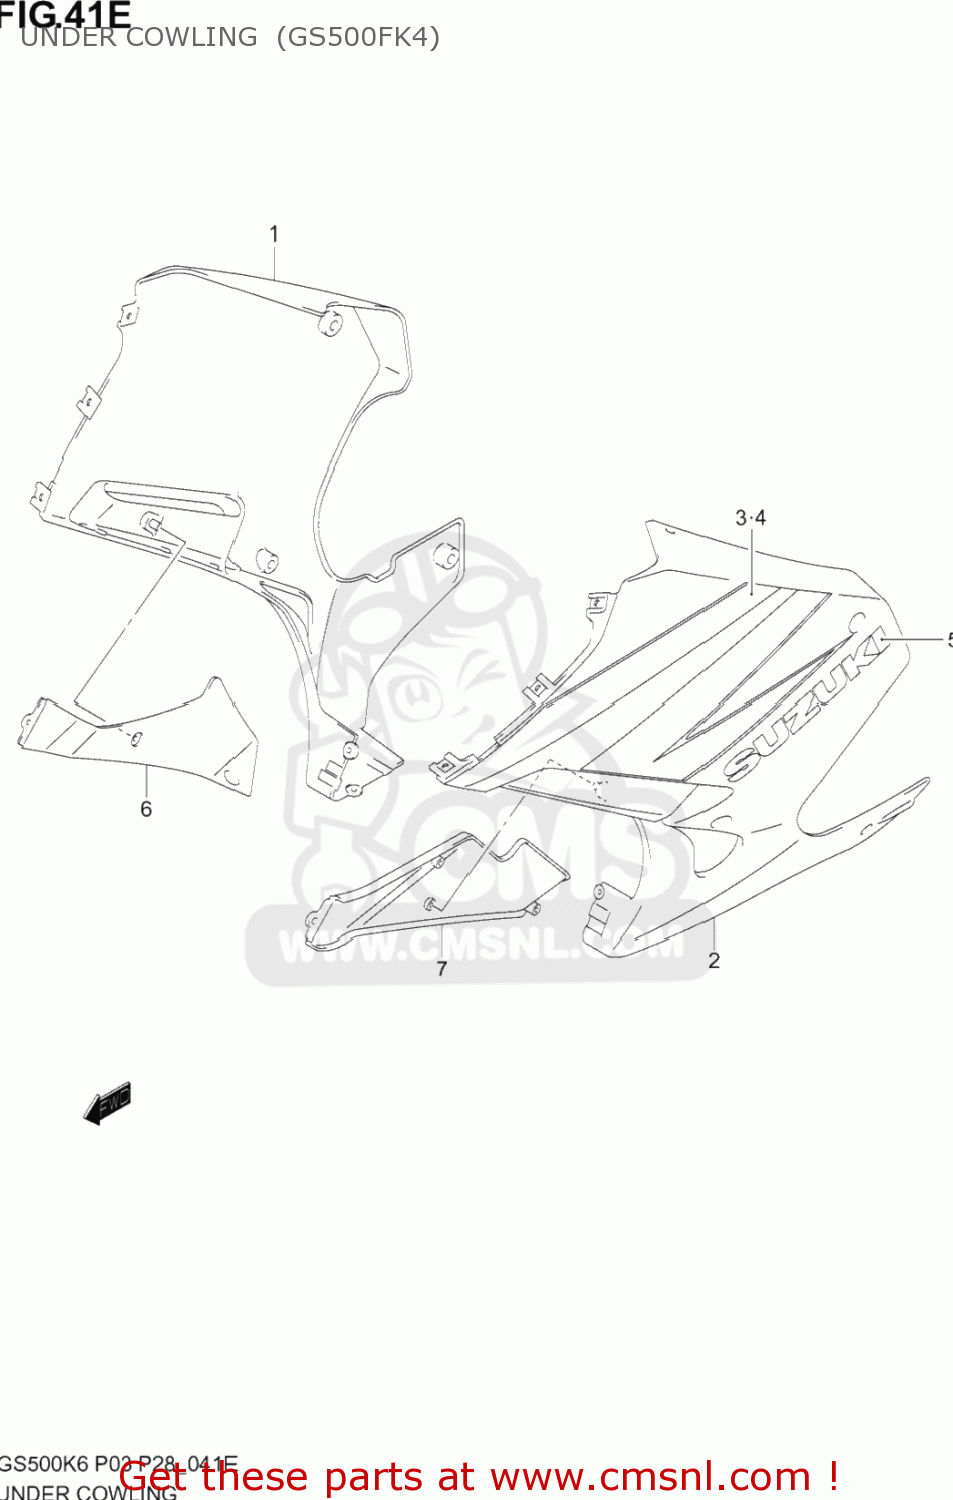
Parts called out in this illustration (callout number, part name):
1	COWL, UNDER RH (BLUE)
2	COWL, UNDER LH (BLUE)
3	TAPE SET RH
4	TAPE SET LH
5	EMBLEM,SUZUKI
6	COWL, INNER RH
7	COWL, INNER LH
8	SHIELD,UNDER C
9	SHIELD,UNDER C
10	SHIELD,UN. HEA
11	SHIELD,UN.HEAT
